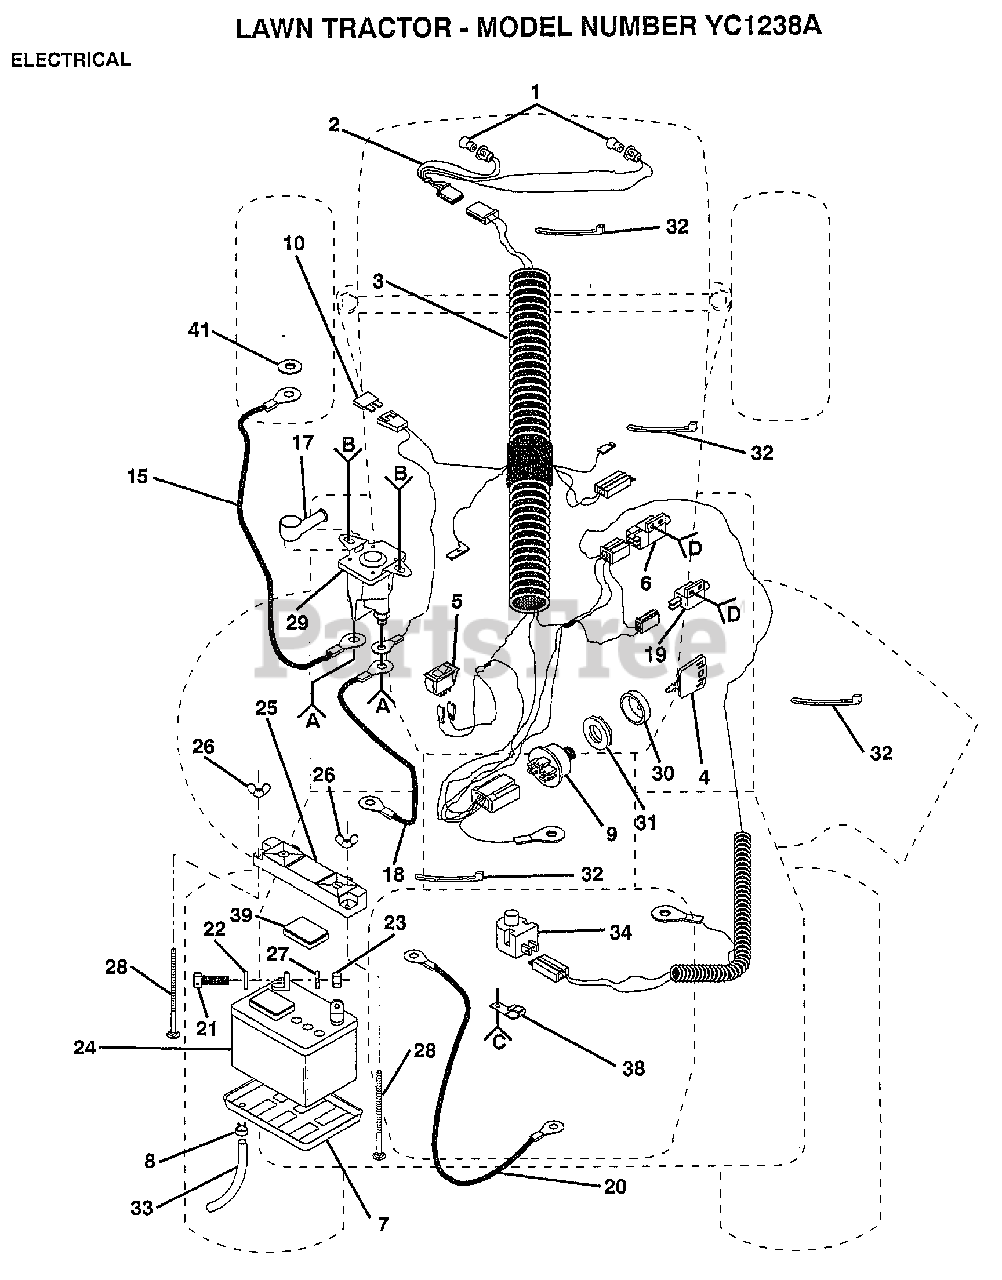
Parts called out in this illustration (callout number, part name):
2	HARNESS T
3	"HARNESS,WIRING"
4	KEY
5	SWITCH LT
6	SWITCH-INTER. GT
7	"TRAY T, BATTERY"
8	HOSE CLAMP T
10	FUSE HYT
12	NUT
13	BOLT
14	NUT
15	CABLE T
18	STARTER CABLE GT
19	SWITCH INTERLOCKT
20	CABLE ASM.
21	BOLT LT
22	WASHER
27	LOCKWASHER
28	BOLT
32	WIRE TIE
34	SWITCH SEAT
35	SCREW
37	"NUT,KEPS"
39	"CAP,BATTERY "
